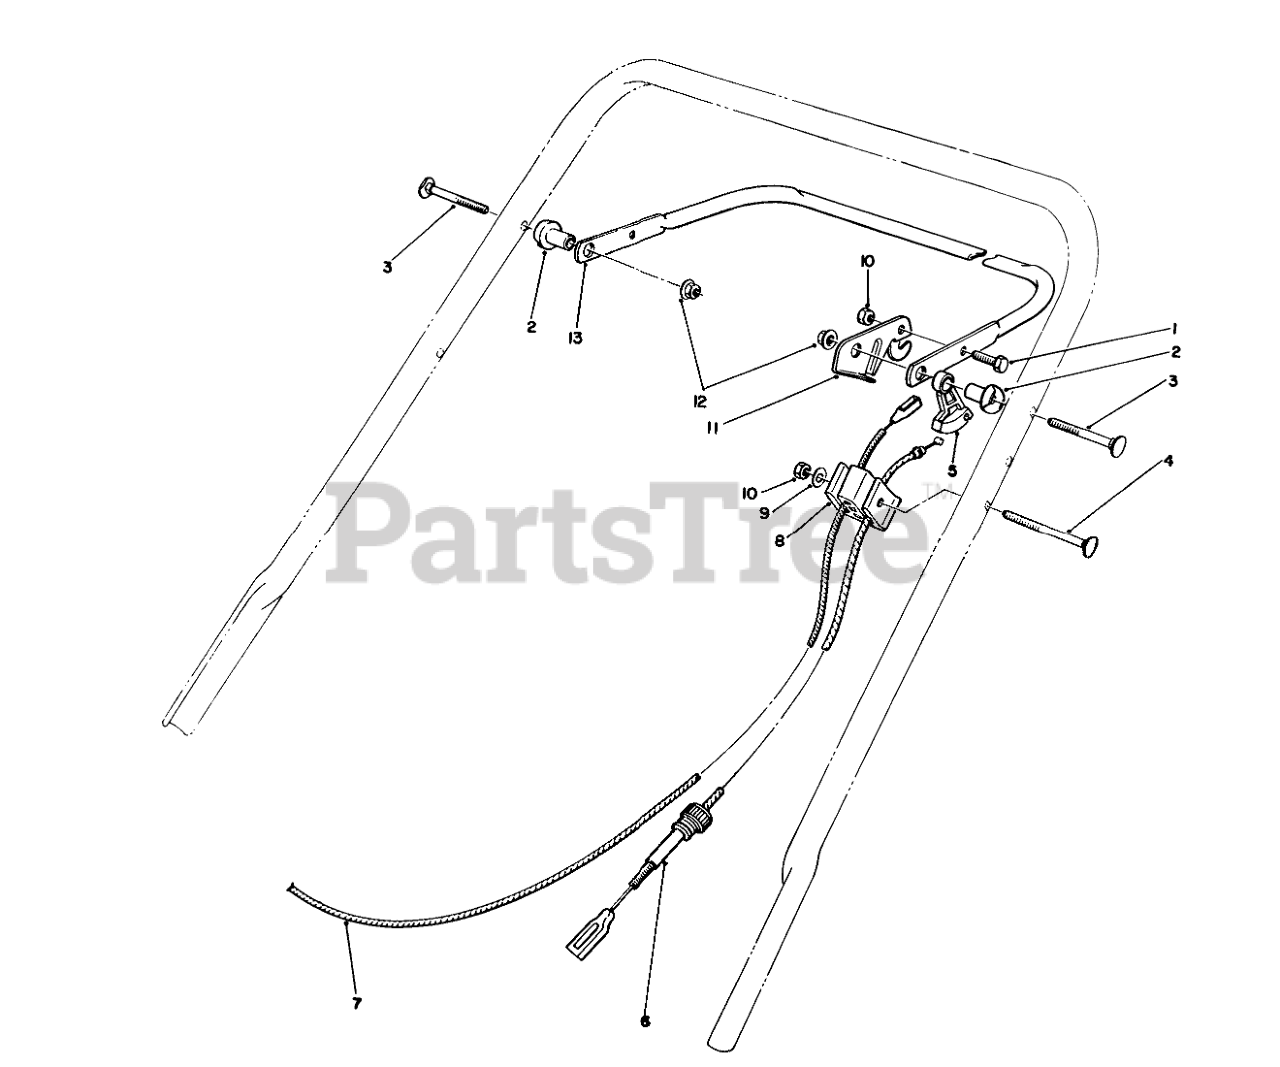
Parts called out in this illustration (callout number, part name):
1	SCREW-HH
2	SPACER-SUPPORT
3	5/16-18 X 2 HNDLE SCREW
4	HANDLE SCREW
5	LEVER-TRACTION
6	CABLE-TRACTION
7	BRAKE CONTROL
8	SUPPORT-CABLE
9	WASHER-FLAT
10	NUT-LOCK, NI
11	LEVER-CONTROL
12	NUT-LOCK, NI
13	Bar-Control
